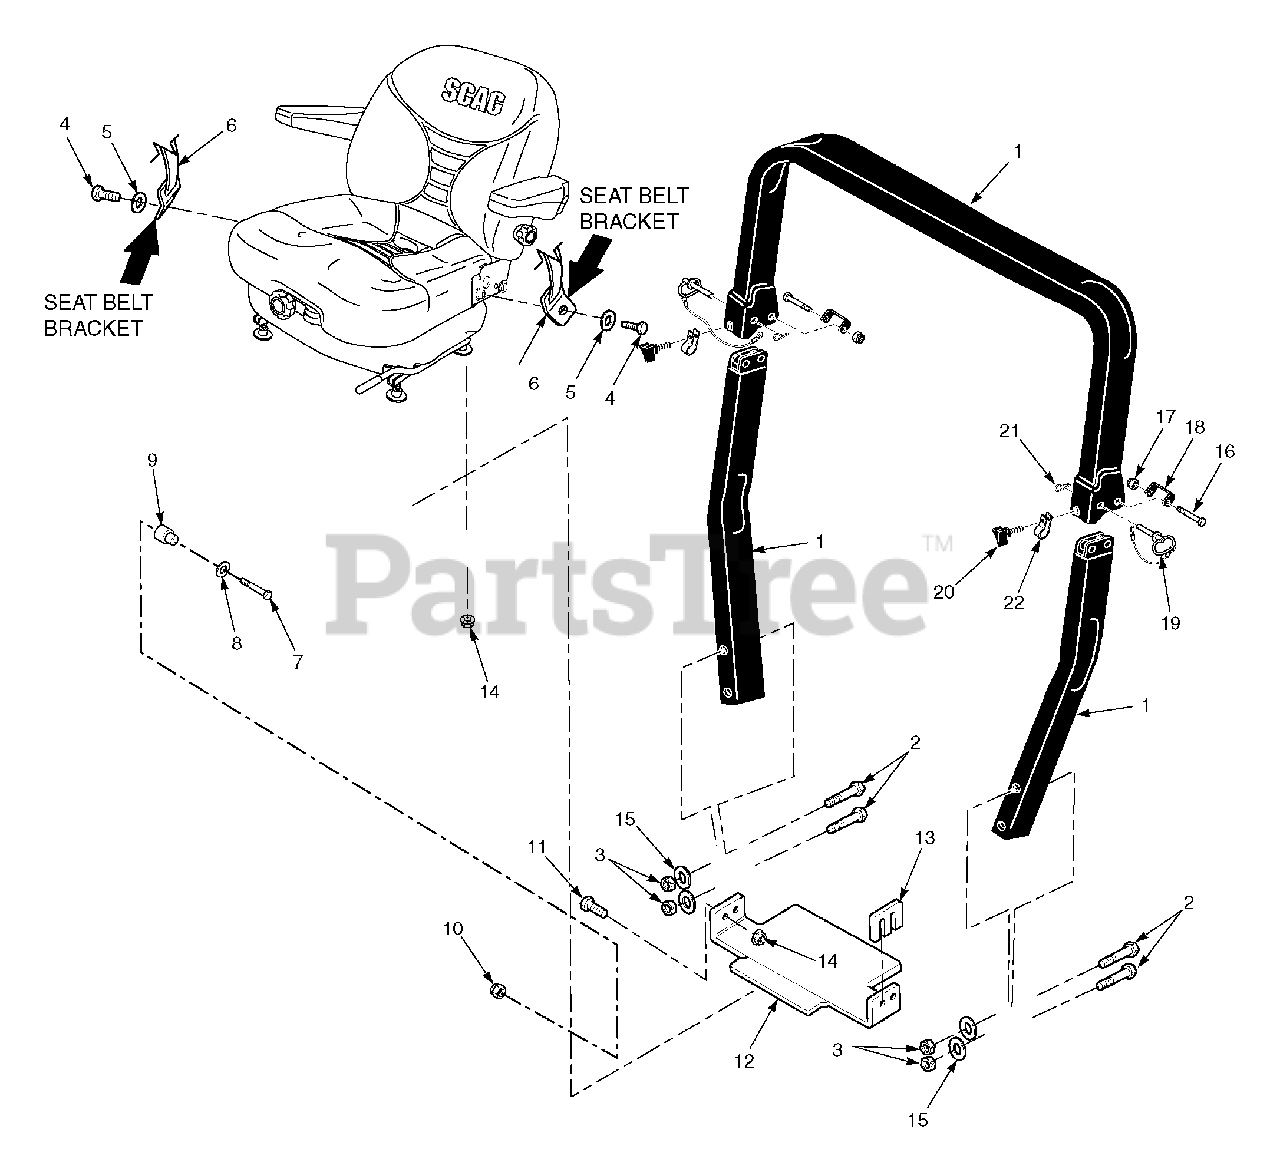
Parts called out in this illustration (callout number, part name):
1	STT, ROPS Accessory
2	Bolt, Hex Head 1/2-13 x 4-1/2"
3	Nut, Center Lock 1/2-13
4	Bolt, Hex Head 7/16-20 x 1"
5	Flatwasher, 7/16-.500 x 1.25 x .083
6	Seat Belt
7	Bolt, Hex Head 3/8-16 x 2"
8	Flatwasher, 3/8-.391 x .938 x .105
9	Sleeve, Seat Base Mounting
10	Nut, Elastic Stop 3/8-16
11	Bolt, Hex Head 5/16-18 x 1"
12	Bracket, Seat Hold Down with Decal
13	Lockwasher, 7/16
14	Nut, Serrated Flange 5/16-18
15	Flatwasher, 1/2-.562 x 1.375 x .109
16	Bolt, Hex Head 1/2-13 x 3-1/2"
17	Nut, Center Lock 1/2-13
18	Bracket, Stop
19	Pin
20	Thumb Screw, 5/16-18 NC x 3-4"
21	Hair Pin, Cotter
22	Clamp
